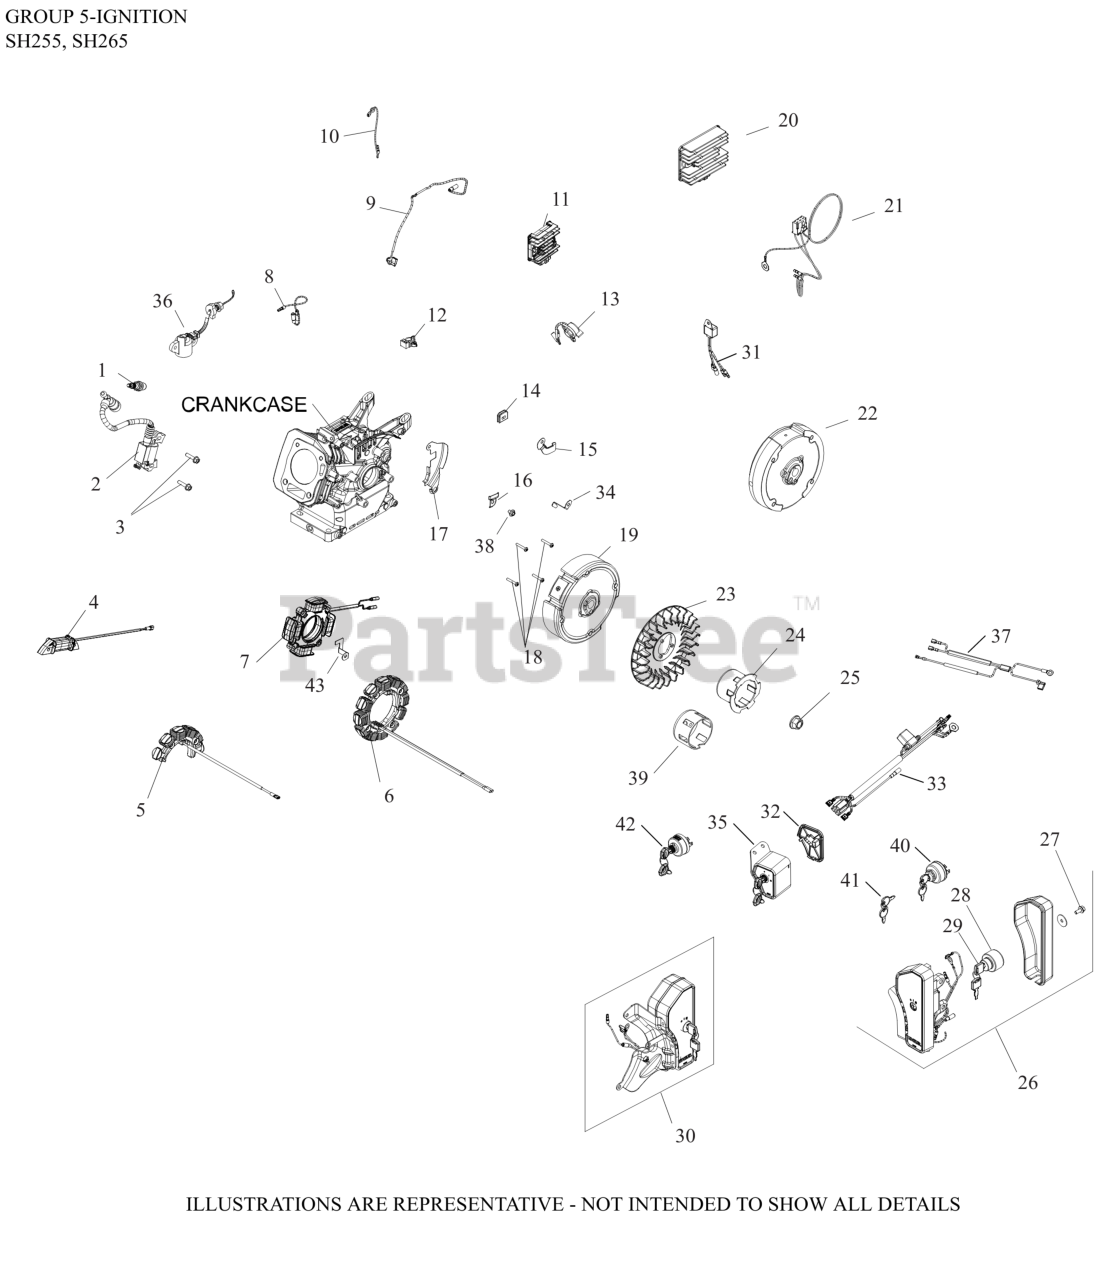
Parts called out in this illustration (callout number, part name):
1	SPARK PLUG
2	MODULE, IGNITION
3	SCREW, M6 X 25-(#25086436S)
8	LEAD, OPTIONAL EQUIPMENT
9	LEAD, GROUND TO KILL
12	CLIP, WIRE HARNESS
13	SWITCH, IGNITION
19	FLYWHEEL ASSEMBLY
23	FAN, FLYWHEEL
25	NUT, FLYWHEEL (W/SERRATIONS)
39	STARTER CUP
